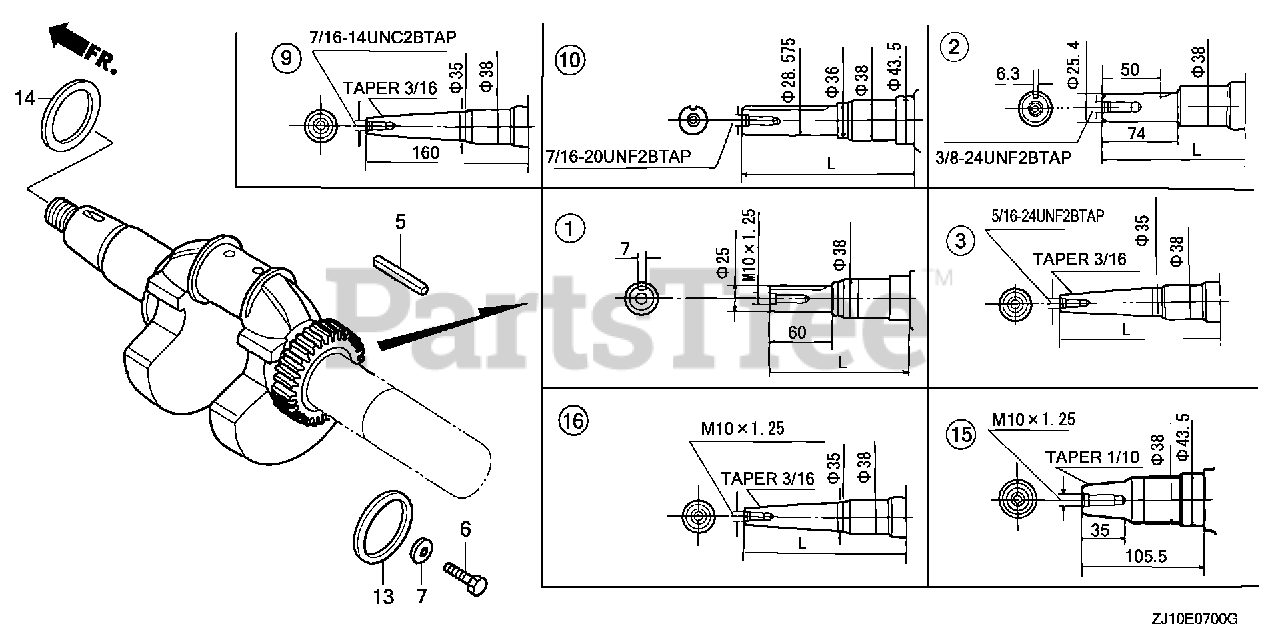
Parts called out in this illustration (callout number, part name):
2	CRANKSHAFT (L=139.5)
5	KEY (6.3X6.3X43)
13	WASHER, CRANKSHAFT THRUST (38.5X54.0X1.0)
